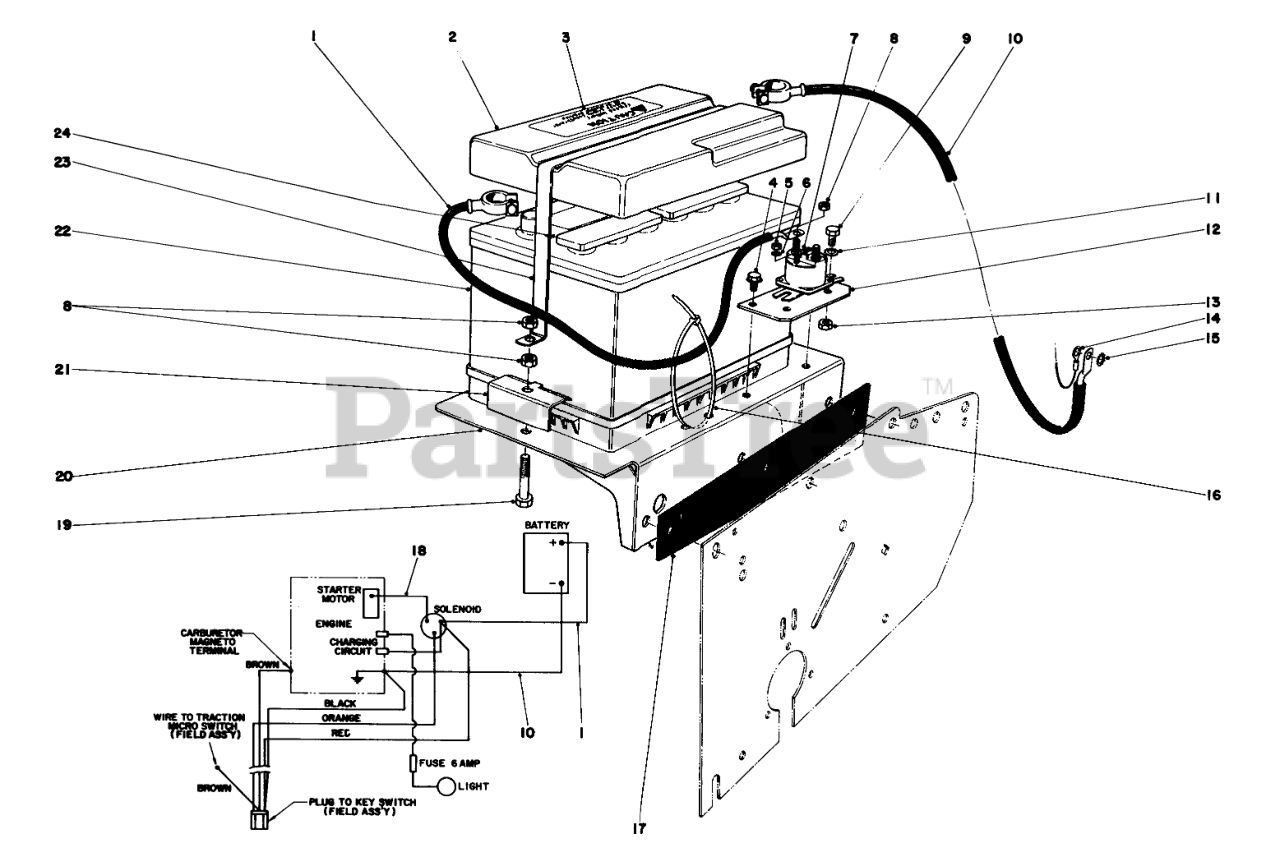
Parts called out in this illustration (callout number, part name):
1	BATT-SOLENOID CABLE
2	Cover Battery (Incl. Ref. #3)
3	Decal
4	SCREW-HWH
5	NUT-HEX
6	WASHER-LOCK, INT
7	SOLENOID
8	NUT-HEX
9	SCREW-HH
10	BATT-GROUND CABLE
11	WASHER-LOCK/EXT
12	Bracket Solenoid
13	NUT-LOCK, NI
14	TERMINAL - RING
15	WASHER-LOCK
16	TIE-CABLE
17	Batery Isolation Pad
18	STRT MTR-SOLNOID WIRE
19	SCREW-HH
20	Battery Mounting Plate
21	BATTERY CLAMP
22	Battery
23	Strap Battery
24	PUSH-ON BATTERY CAP
